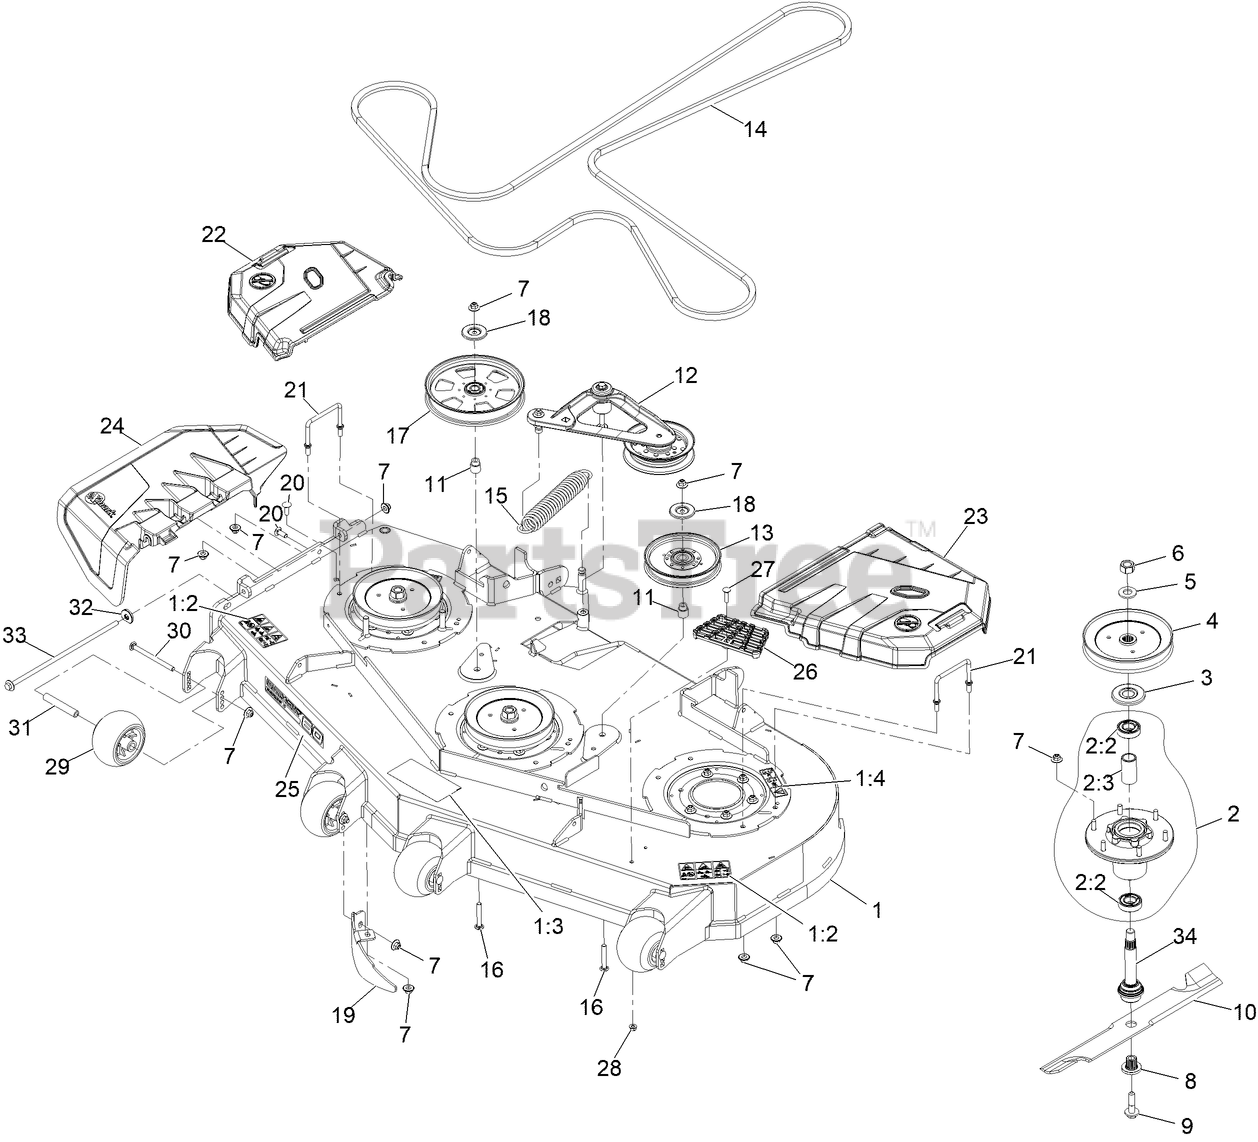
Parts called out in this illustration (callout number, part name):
1	Deck ASM, W/Decals 60
1:2	DECAL-DANGER THROWN OBJECTS
1:3	DECAL-ANTI-SCALP-BELT ROUTING
1:4	DECAL-COVER, MISSING
2	ASM-CUTTER HSG WITH BEARINGS
2:2	BEARING-BALL
2:3	SPACER-BEARING
3	GUARD,BEARING TOP .989
4	SHEAVE,BLADE DRIVE 7.25
6	NUT-HEX
7	Nut-Nyloc 3/8-16 Flg
8	BUSHING,SPLINED
9	SCREW,SEMS 1/2-20 X 2.19
10	Blade-Extreme 2, 20.50"
11	BUSHING-IDLER
12	DECK IDLER ASM
13	IDLER-PULLEY
15	SPRING-EXTENSION
16	SCREW-CARR
17	PULLEY-IDLER, FLAT
18	SHIELD-DUST
19	DOGLEG - LZ60
20	SCREW-CARR
21	WIREFORM-COVER
22	SHIELD, RT
23	SHIELD, LT
24	Chute-Deck Discharge
25	DECAL, 604
26	STEP-DECK
27	Bolt-Carriage 5/16-18 X 1 1/4
28	NUT-HF, NI
29	ROLLER-SCALP, ANTI
30	BOLT-CARR
31	SPACER-AXLE
32	Retainer, Chute
33	Pin, Chute
34	ASM-SPINDLE AND SEAL
